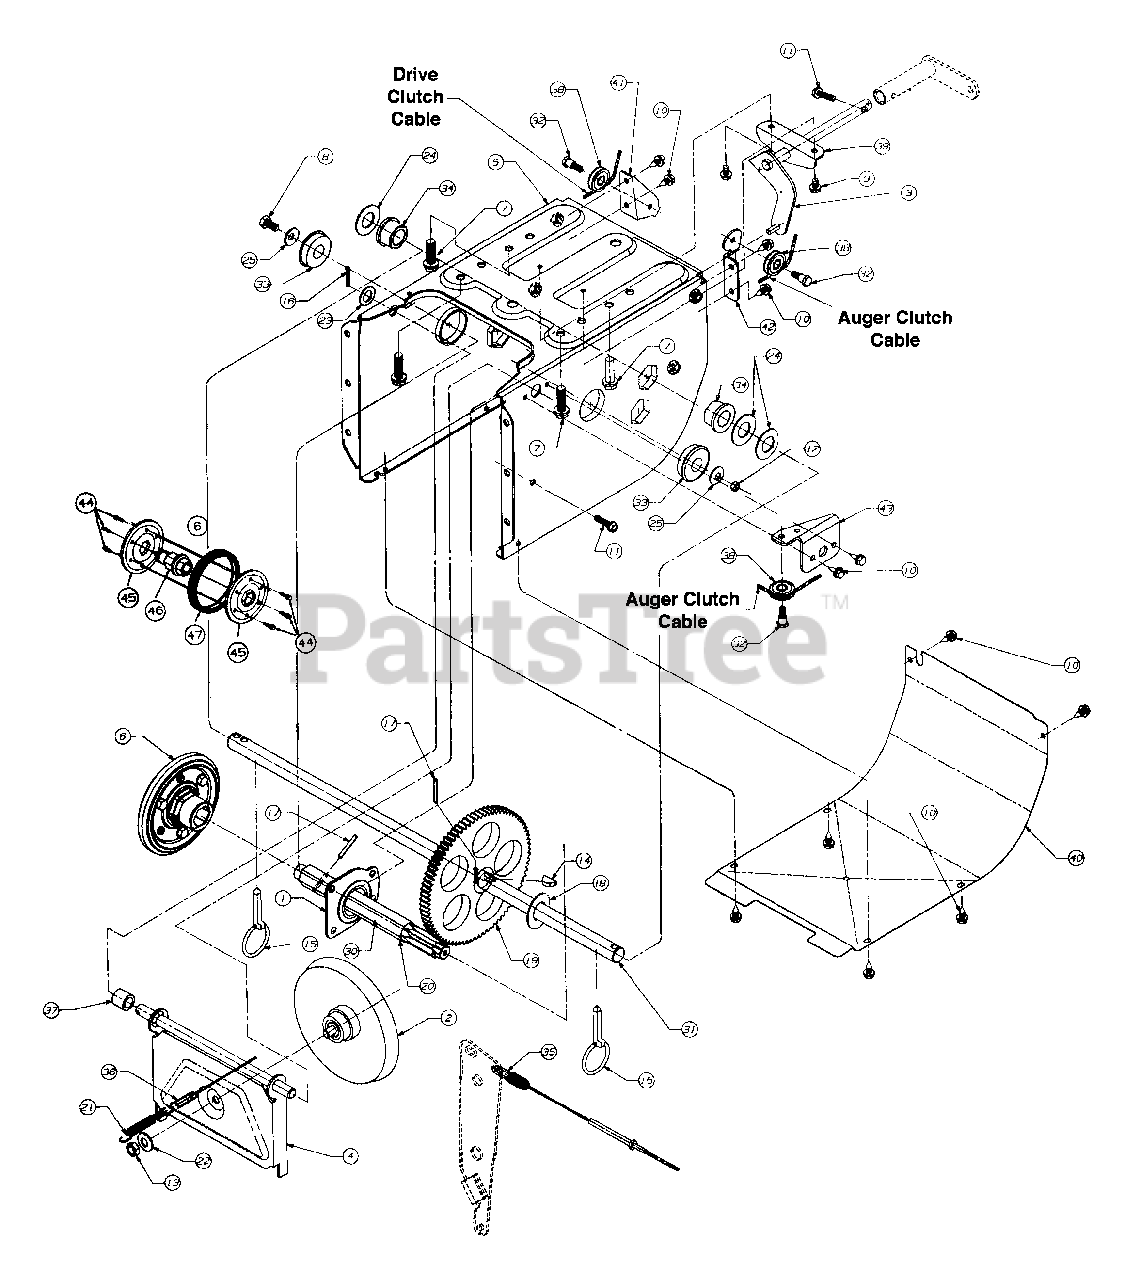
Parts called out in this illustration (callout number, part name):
1	Bearing Ass'y.
2	Ass'y., Friction Wheel Disc
3	Rod Shift, Wheel Drive
4	Brkt. Ass'y. Friction Wheel
7	Hex Self-Tap Screw
8	Screw-Hex Lock
9	Scr., Hex Wash. Hd., TT 1/4-20 x .5"
10	Hex Self-Tap Scr.
11	Screw, Hex
12	Nut-Jam Hex
13	Nut, Hex
14	Key
15	Pin, Klick
16	Pin, Cotter
17	Pin, Roll
18	Washer-Flat
20	Shaft, Hex
21	Extension Spring
22	Washer, Bell
23	Flat Washer
24	Washer, Flat
25	Washer, Bell
30	Lubricant
32	Screw, Shoulder
33	Bearing, Ball
34	Flange Bearing
35	Cable, Auger
36	Cable, Clutch
37	Spacer
38	Roller, Cable
42	Brkt., Auger Clutch Cable Guide
43	Brkt., Front Support Guide
44	Hex Wash Hd. TT-Tap Scr. 1/4-20 x .5" Lg.
45	Friction Plate
46	Friction Wheel Hub
47	Friction Wheel Rubber
